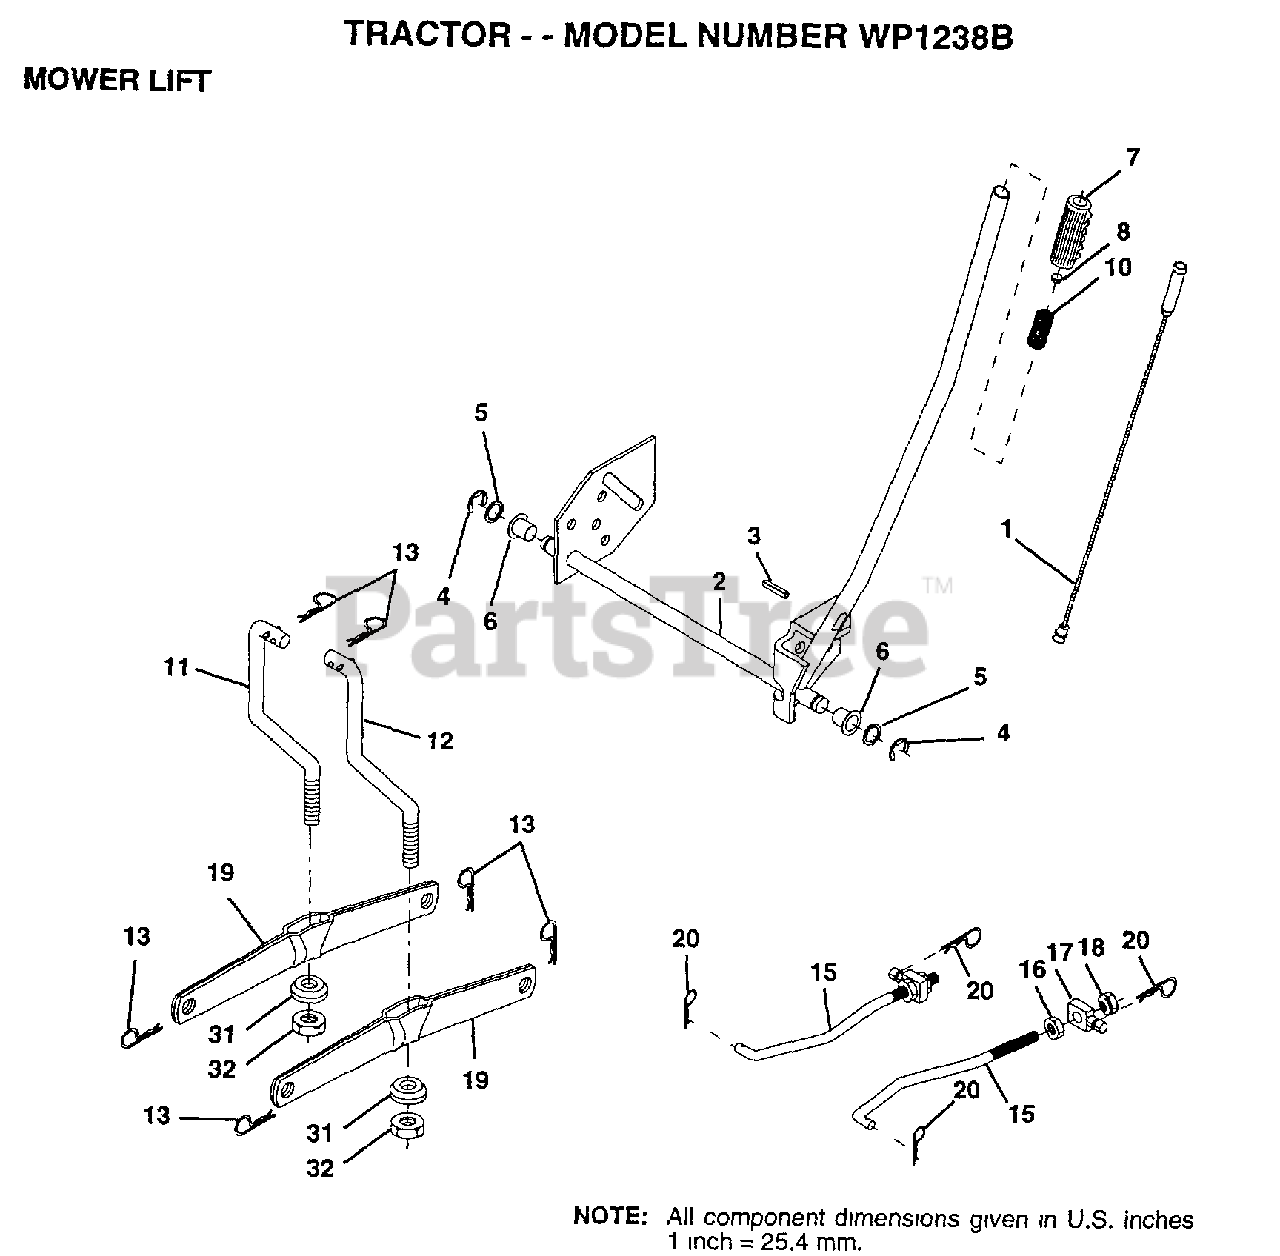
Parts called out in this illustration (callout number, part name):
1	WIRE ASM
3	PIN-GROOVE LT
5	WASHER
6	NYLON BEARING
7	GRIP
15	LINK.FRONT
16	NUT
17	TRUNION
18	NUT.LK.W/WSH.1/2.
19	ARM SUSP REAR
20	RETAINER.SPRING
31	BEARING PVT LH
32	NUT.CROWNLOCK.3/8
